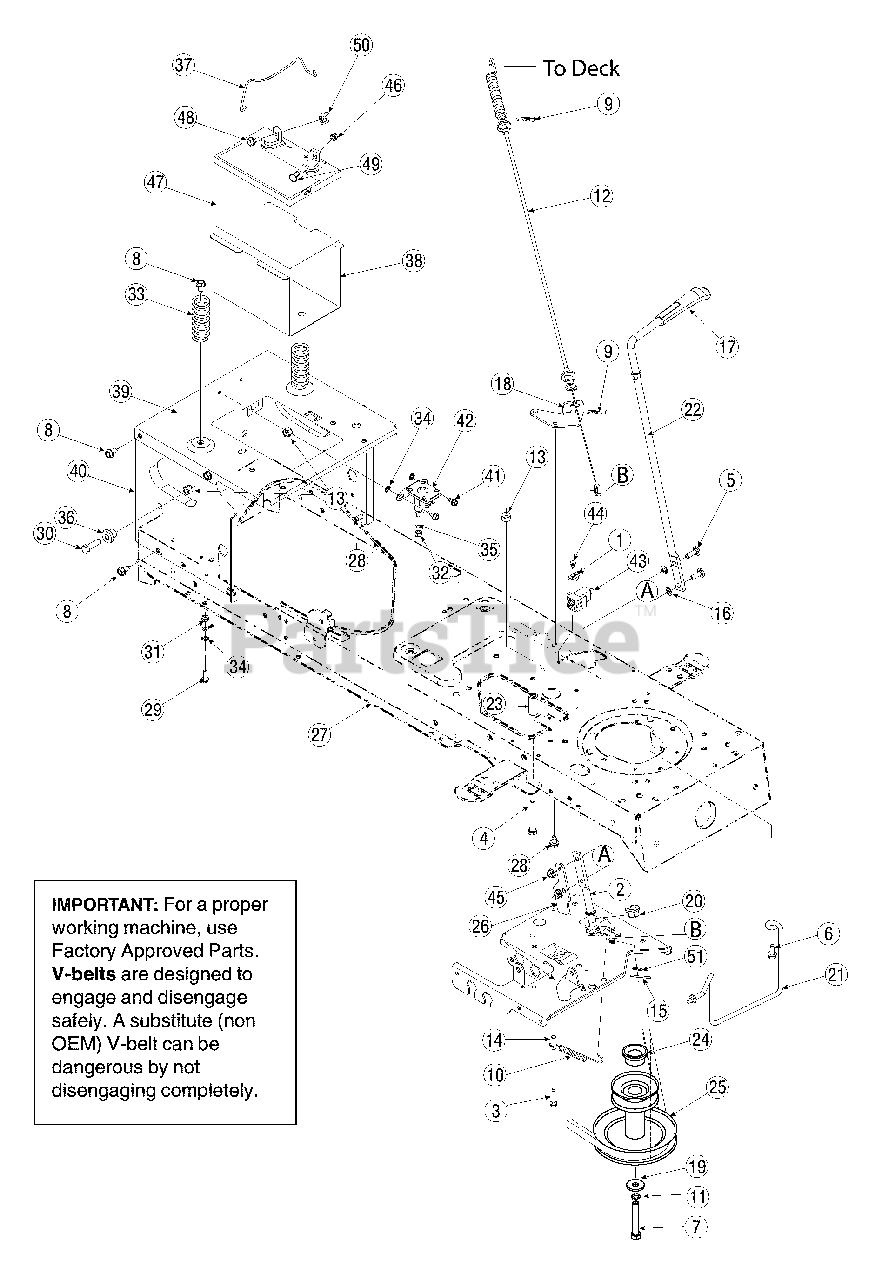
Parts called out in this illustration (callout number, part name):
1	Plate, Switch
2	Lever Assembly, Engagement
3	Screw, 1/4-20 x 1.250
4	Screw, 3/8-16, 2.50
5	Screw, Carriage, 5/16-18, 1.00
6	Screw, 5/16-18 x.750
7	Screw, 7/16-20, 3.25, Gr5
8	Screw, 5/16-12, 0.750
9	Click Pin
10	Extension Spring,.38OD x 3.9LG
11	Lock Washer, 7/16
12	Deck Engagement Cable
13	Nut, Flange Lock, 3/8-16, Gr F, Nylon
14	Spacer,.260 x.372 x 1.030LG
15	Pin, Cotter, 1/8 x 1.25
16	Nut, Speed,.3125 ID
17	Knob, PTO
20	Bearing, Flange, Hex Split.500 ID
21	Keeper Rod, Belt
23	Spacer,.385 ID x.635 OD x 1.54
24	Spacer, 1.010 x 1.400 x.825
25	Pulley, Engine, 3.56 x 6.12 Diameter
29	Screw, 1/4-20, 0.750
30	Screw, 3/8-16, 1.25, Gr5
31	Nut, Flange Lock, 1/4-20, Gr F, Nylon
32	Nut, Hex, 1/4-20, Gr5
33	Spring, Compression, 1.28 OD x 3.125
34	Washer, Lock, 1/4, External
35	Washer, Lock, 1/4
36	Spacer, Shoulder,.38 x 1.0 x.70
37	Hold Rod, Battery
41	Screw, 1/4-20, 0.50
42	Solenoid, 12V, 100 Amp
43	Switch, Interlock
44	Screw, #10-16,.50
45	Nut, Flange, Lock Nut, 5/16-18
46	Nut, Sems, 1/4-20
47	Battery, 190 CCA
48	Screw, Shoulder,.250 x.15, 1/4-20
49	Screw, Carriage, 1/4-20,.75
50	Nut, Wing, 1/4-20
51	Flat Washer,.344 x.688 x.065
